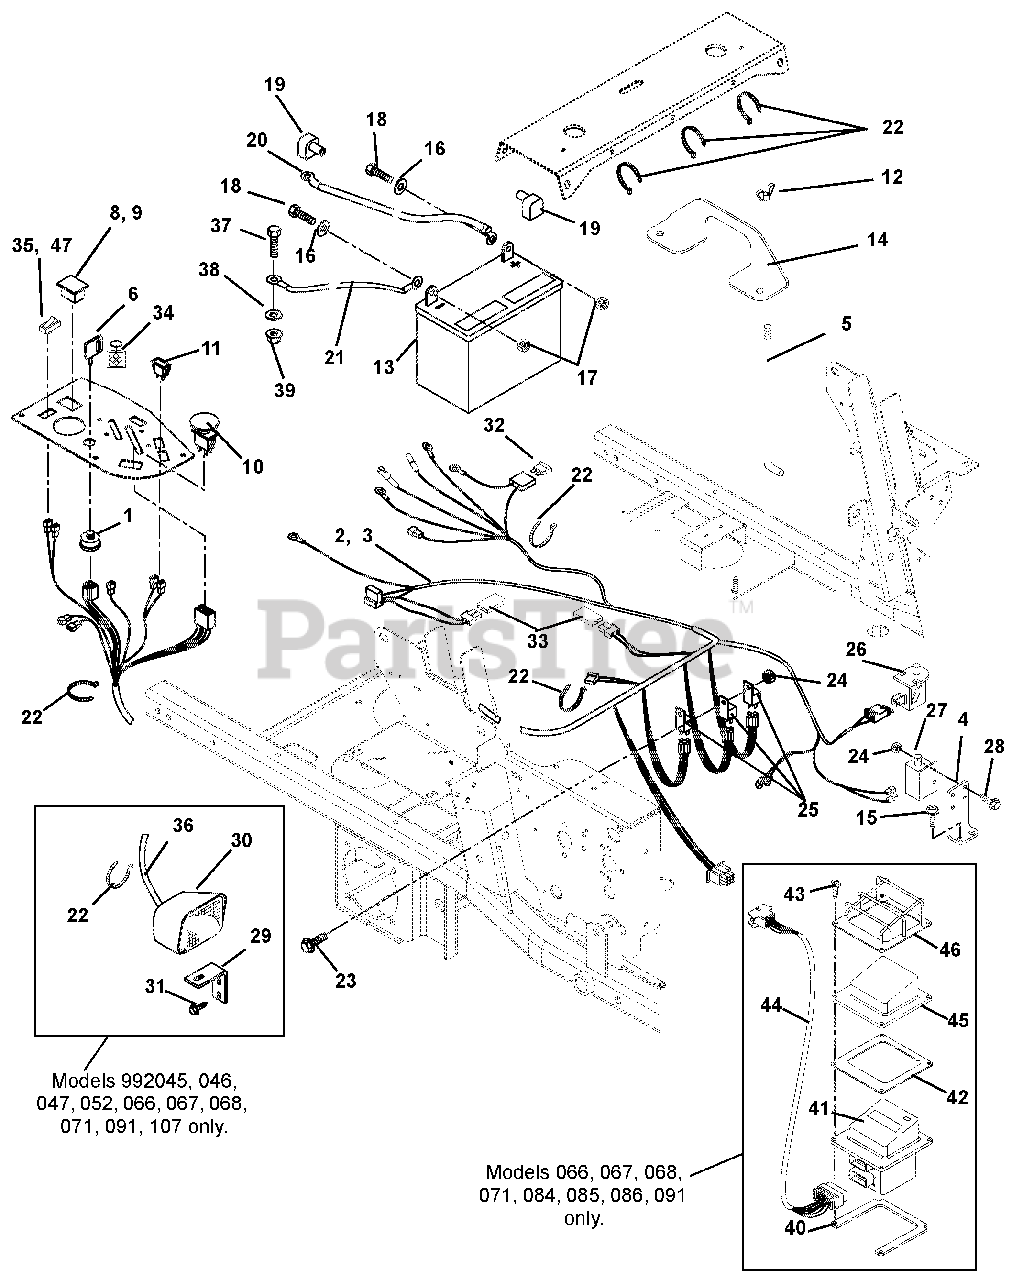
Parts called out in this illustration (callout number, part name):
1	Switch, Ignition
2	Harness, Z-6 Pin Wiring (EYE-Q) (045, 046, 047, 052, 066, 067, 068, 071, 087, 088, 089, 102, 103, 105,
3	Harness, EFI-Monster Wiring (EYE-Q) (091, 107)
4	Mount, Safety Switch
5	Rod, Battery Holddown .25 x 6.62
6	Key, with Shield
7	Ignition Key Set
8	Plug, Hour Meter (066, 067, 068, 071, 084, 085, 086, 091)
9	Hour Meter (045, 046, 047, 052, 066, 067, 068, 071, 087, 088, 089, 102, 103, 105, 107)
10	Switch, PTO Clutch
11	Light-Indicator Kit (045, 046, 047, 052, 066, 067, 068, 071, 087, 088, 089, 102, 103, 105, 107)
12	Nut-Locking Wing .25-20
13	Battery, 12V
14	Hold Down, Battery
15	Screw-Tapping .25-20 x .50 Hex Washer Head
16	Washer-Flat-Steel .281 x .620 x .065
17	Nut-Locking-Top-Flange .25-20
18	Bolt-Hex .25-20 x .75 Grade 5
19	Battery Terminal Boot, Red
20	Starter Cable 13 in.
21	Ground Cable
22	Cable Tie (045, 046, 047, 052, 066, 067, 068, 071, 087, 088, 089, 102, 103, 105, 107)
23	Screw-Machine 10-24 x .50 Hex Washer Head
24	Nut-Locking-Nylon 10-24 With Insert
25	Relay (Included with Harness)
26	Switch- Snap Mounting
27	Switch-Single Pole
28	Screw-Machine 10-24 x .75 Hex Washer Head
29	Bracket, Headlight Mounting Left (045, 046, 047, 052, 066, 067, 068, 071, 084, 085, 086, 091, 104, 106,
30	Headlight (045, 046, 047, 052, 066, 067, 068, 071, 084, 085, 086, 091, 104, 106, 107, 108)
31	Screw-Tapping .38-16 x .50 Hex Washer Head (045, 046, 047, 052, 066, 067, 068, 071, 084, 085, 086,
32	Fuse, 30 Amp (Included with Harness)
33	Diode, Connector Shell
34	Key Chain
35	Switch, Light (045, 046, 047, 052, 066, 067, 068, 071, 084, 085, 086, 091, 104, 106, 107, 108)
36	Harness, Headlight Kit (045, 046, 047, 052, 066, 067, 068, 071, 091, 107, 108)
37	Bolt-Hex .31-18 x .75 Grade 5
38	Washer-Flat-Steel .344 x .688 x .065
39	Nut-Locking-Top-Flange .31-18
40	Spacer, Enclosure Mounting (Bottom) (066, 067, 068, 071, 084, 085, 086, 091)
41	Assembly, Eye-Q (066, 067, 068, 071, 084, 085, 086, 091)
42	Gasket, Eye-Q (066, 067, 068, 071, 084, 085, 086, 091)
43	Screw, Machine 10-24 x 1.00 (066, 067, 068, 071, 084, 085, 086, 091)
44	Harness, Eye-Q (066, 067, 068, 071, 084, 085, 086, 091)
45	Guard, Element (066, 067, 068, 071, 084, 085, 086, 091)
46	Guard, Vinyl Eye-Q (066, 067, 068, 071, 084, 085, 086, 091)
47	Switch, Blank (087, 088, 089, 102, 103, 105)
